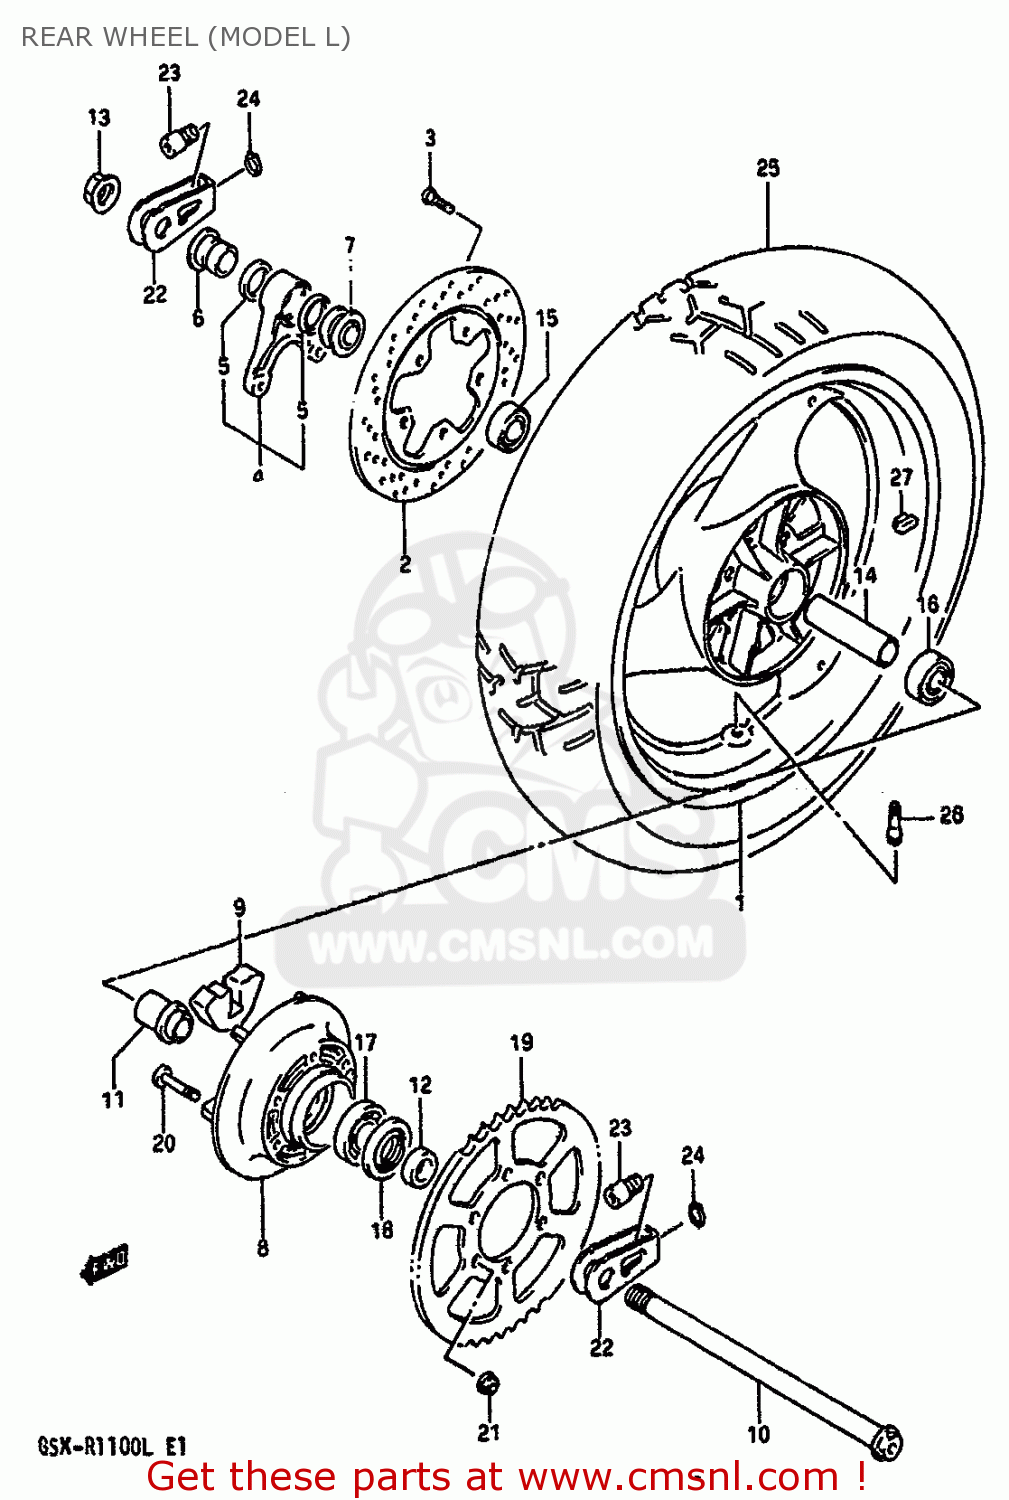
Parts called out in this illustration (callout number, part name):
1	WHEEL,REAR
2	DISC,RR BRAKE
3	BOLT
4	BRACKET,RR CALIPER
5	SEAL,OIL(28X35X5)
6	SPACER,RR CALIPER BRACKET
7	SPACER,RR AXLE,R
8	DRUM,RR SPROCKET
9	ABSORBER,RR HUB SHOCK
10	AXLE,RR
11	RETAINER,RR HUB BEARING
12	SPACER,RR AXLE,L
13	NUT
14	SPACER,RR WHEEL HUB BEARING
15	BEARING(20X47X14)
16	BEARING(20X47X14)
17	BEARING(25X62X17)
18	SEAL,OIL(35X62X8)
19	SPROCKET,REAR
20	BOLT
21	NUT
22	ADJUSTER,CHAIN
23	ADJUSTER,CHAIN
24	CIRCLIP
25	TIRE
26	VALVE ASSY,WHEEL RIM(TR412)
27	BALANCER,WHEEL
